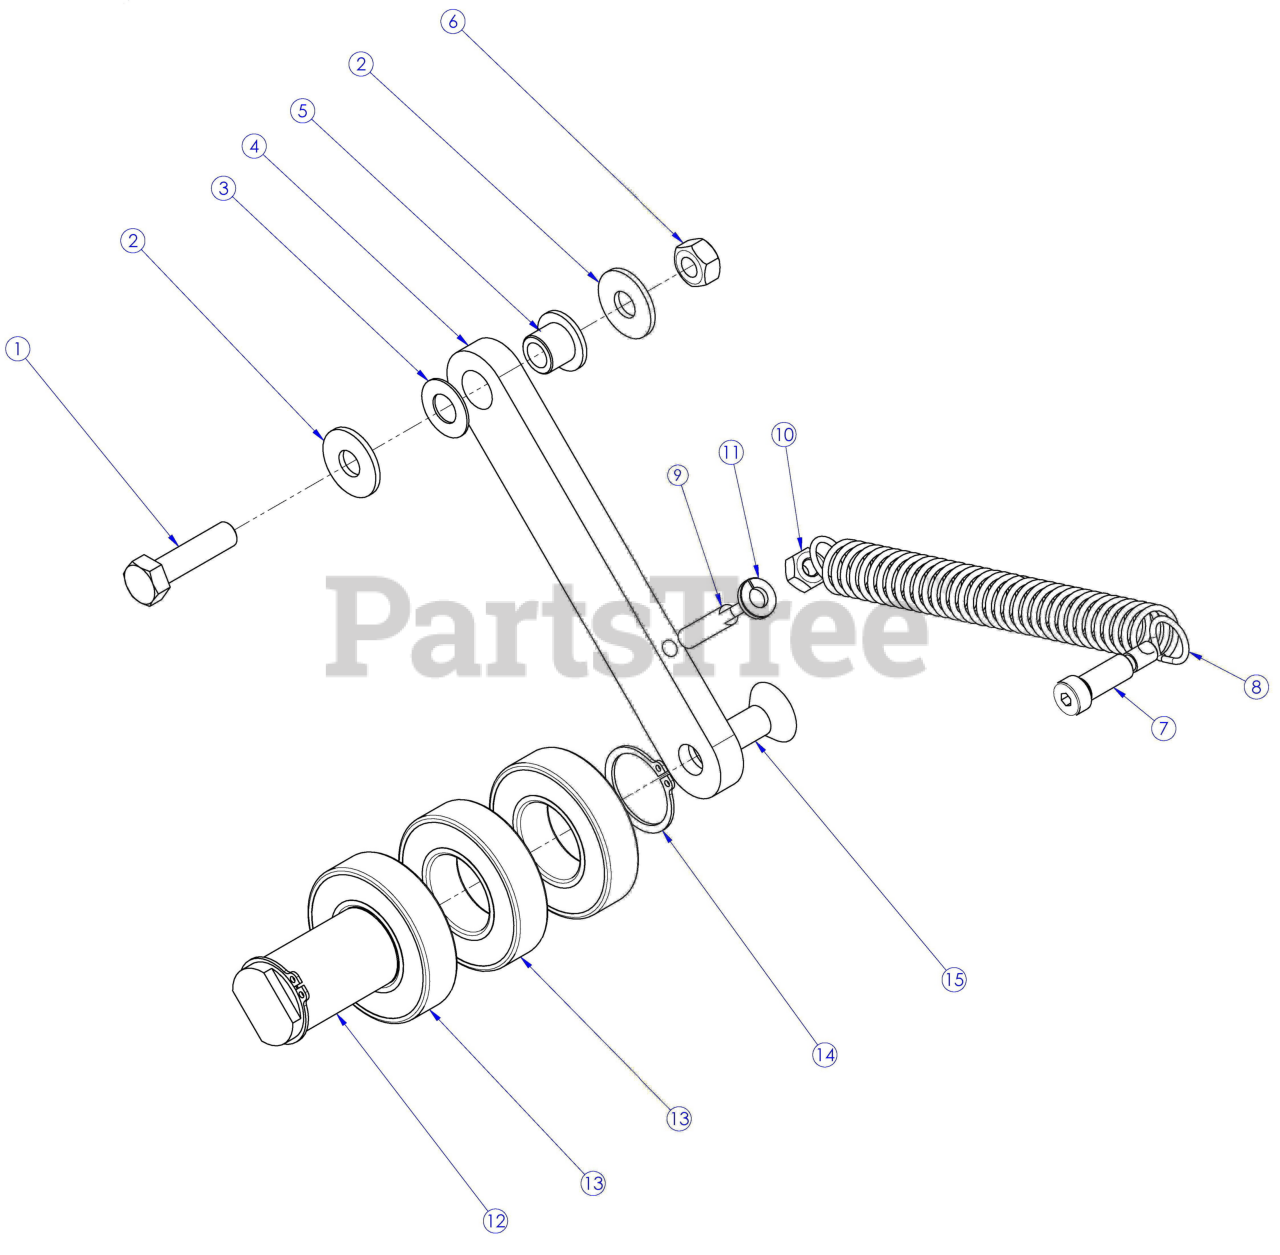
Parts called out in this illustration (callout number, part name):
1	HHB 5/16-24 X 1.25
2	Washer, 5/16" Flat Uss
3	Washer, 3/8" Delrin
4	Arm, Belt Tensioner
5	Flanged Bearing
6	Nut, 5/16-24 Hex, Gr5 Zinc
7	Shsb, 5/16 X 3/4
8	Spring, Extension
9	Spring Anchor, 1/4-20 X
10	Nut, 1/4-20 Hex, Gr5 Zinc
11	Washer, Split 1/4" S.S.
12	Shaft, Blade Belt Tensioner
13	Bearing, 1.00 Id, R16-2Rs
14	Snap Ring, Ext 1.000"
15	Fhs, 3/8-16 X 1 S.S.
